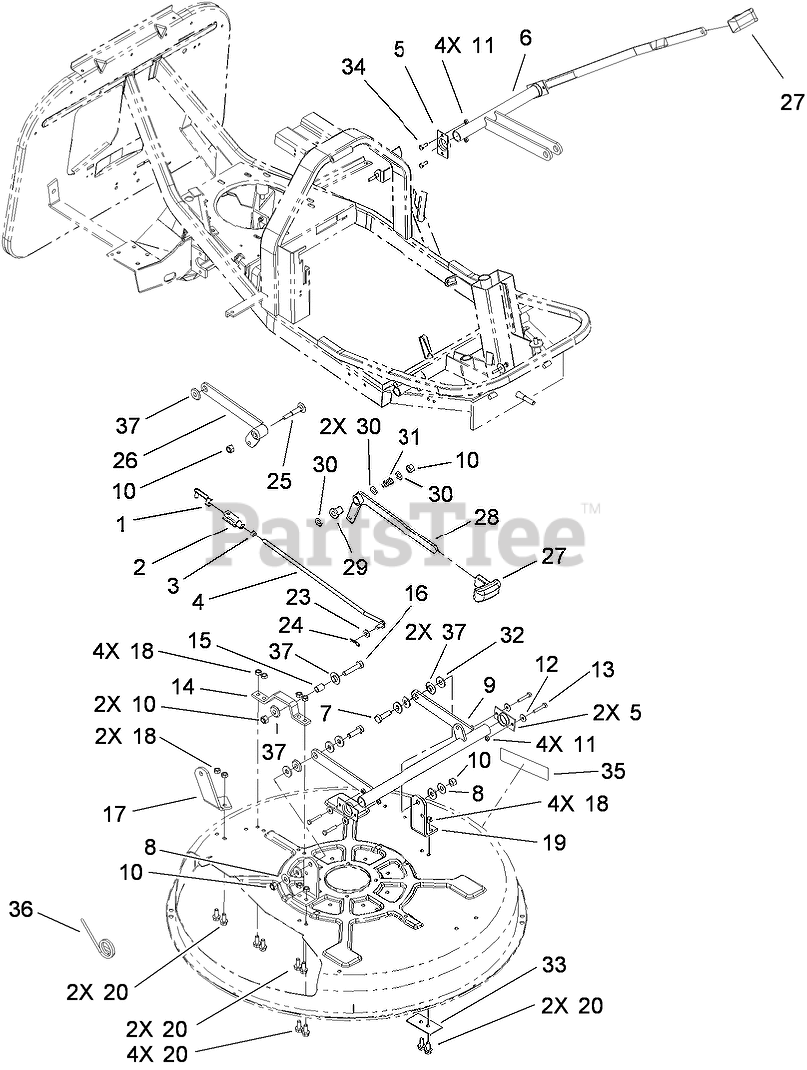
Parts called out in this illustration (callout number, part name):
1	Retainer-Yoke
3	NUT-HEX
4	Rod-Tie
5	Bracket-Support
6	LIFT LEVER ASM
7	Screw-HH
8	Washer-Flat
9	DECK HANGER ASM
10	NUT-LOCK, NI
11	NUT-LOCK
12	Washer-Flat
13	SCREW-HH
14	Bracket-Deck
15	Bushing
16	SCREW-HH
17	Bracket-Deck
18	NUT-LOCK
19	Bracket-Deck
20	SCREW-HHF
23	WASHER-PLAIN
24	Pin-Hair
25	Screw-CARR
26	DECK-HANGER, SUPPORT
27	Handle
28	LEVER-BLADE, CLUTCH
29	Bushing
31	Spring-Compression
32	Washer
34	SCREW-HH
35	DECAL-RECYCLER
36	SPRING-LIFT, DECK
37	BUSHING-LINKAGE, DECK
